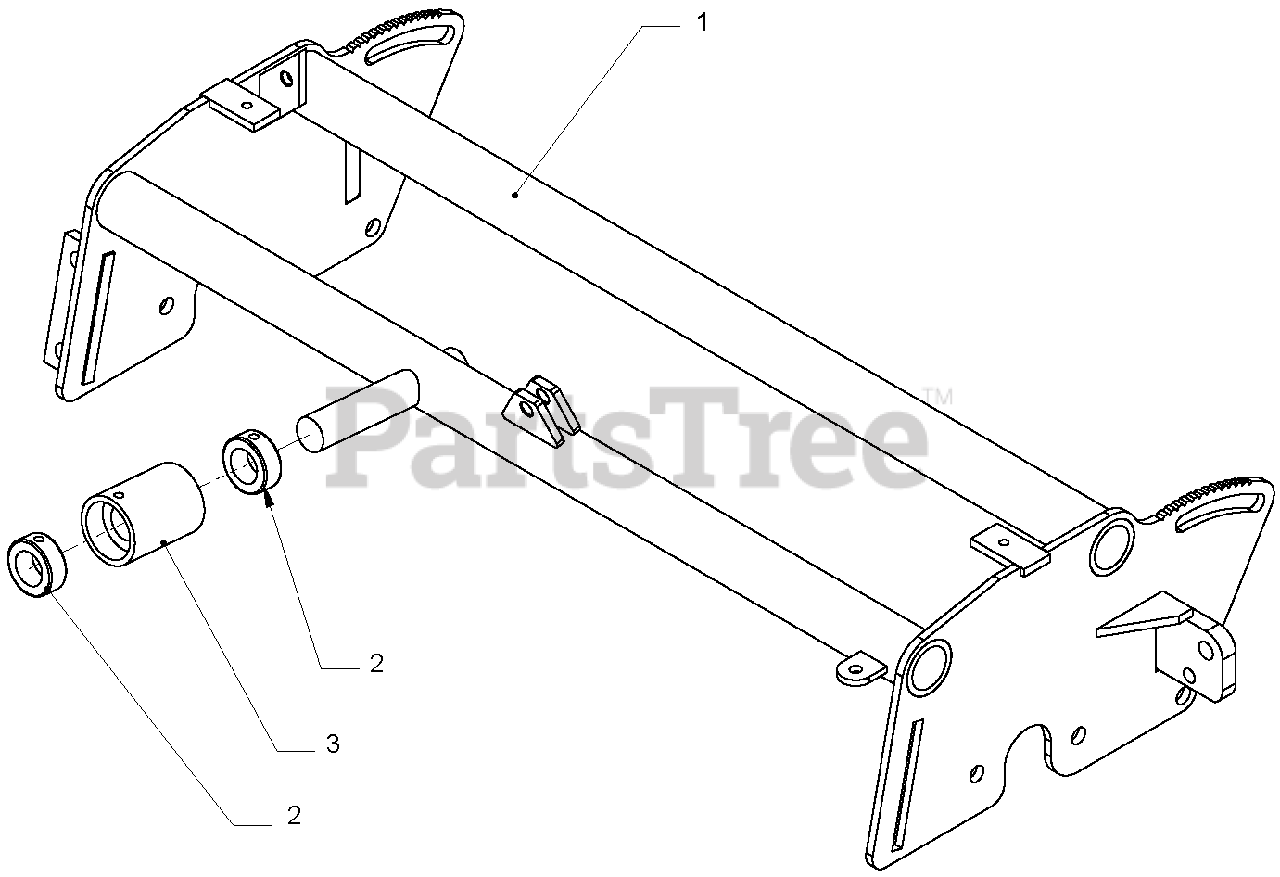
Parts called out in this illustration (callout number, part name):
1	Frame #4 Shown
2	Set Collar, 1"
3	Roller, Nylon
